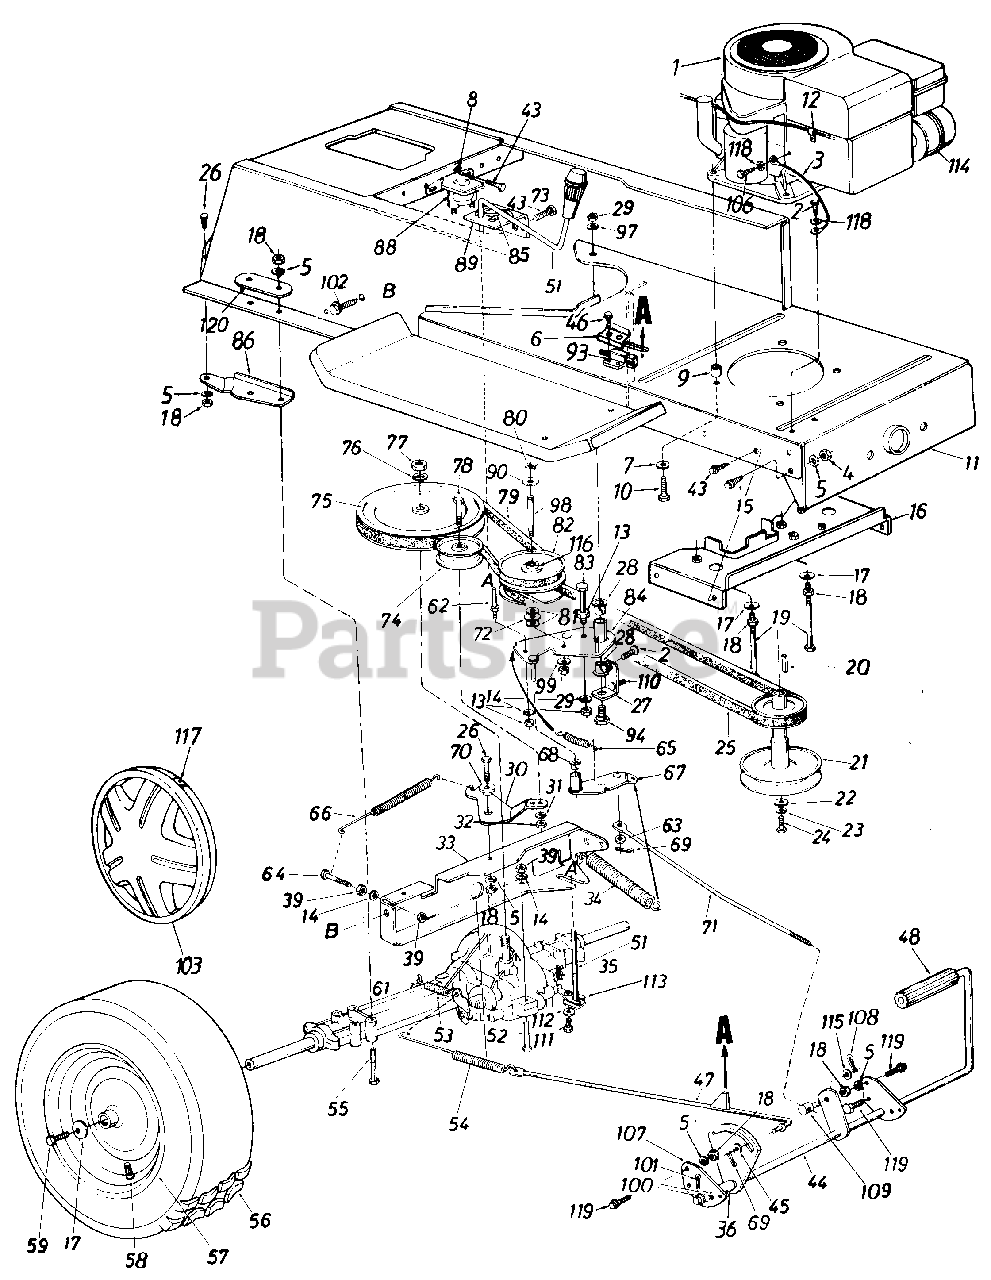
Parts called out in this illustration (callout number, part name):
1	Engine
2	Hex Wash. AB-Tap Scr. 5/16" x .75"
3	Electric Ground Wire
4	Hex Nut 5/16-24 Thd.
5	L-Wash. 5/16" I.D.
6	Switch Plate
7	Fl-Wash. .406" I.D. x 1.25"
8	Ext. L-Wash. 1/4" I.D.
9	Spacer
10	Hex L-Wash. Tap Scr. 3/8-16 x 1.5 Lg.
11	Lower Frame Ass'y.
12	Speed Clip
13	Hex Nut 1/4-20 Thd.
14	L-Wash. 1/4" I.D.
15	Rib Neck Bolt 5/16-24 x .84" Lg.
16	Belt Guard Brkt. Ass'y.
17	Bell-Wash. .345" I.D. x .88"
18	Hex Nut 5/16-18 Thd.
19	Hex Bolt 5/16-18 x 4.0"
20	Sq. Key 1/4" x 1/4" x 2.00"
21	Engine Pulley
22	Fl-Wash. 7/16" I.D. x 1.25"
23	L-Wash. 7/16" I.D.
24	Hex Bolt 7/16-20 x 1.50" Lg.
25	Variable-Speed Belt
26	Hex Bolt 5/16-18 x .75" Lg.
27	Bearing Shaft Bracket Ass'y.
28	Flanged Nyliner Brg. 5/8" I.D. x .88" Lg.
29	Hex Nut 3/8-24 Thd.
31	L-Wash. 3/8" I.D.
32	Hex Nut 3/8-24 Thd.
33	Transaxle Support Brkt.
34	Ext. Spring .94" O.D. x 7.58"
35	Inter. Cott-Pin
36	Spacer.63" I.D.
39	Hex Nut 1/4-28 Thd.
43	Hex Wash. Hd. S-Tap Scr. 1/4-20 x .50" Lg.
44	Clutch/Brake Pedal Ass'y.
45	Fl-Wash.
46	Truss Mach. Scr. B-Tap Scr. #10 x .5" Lg.
47	Brake Rod Ass'y.
48	Foot Pad
51	Shift Lever Ass'y.
52	Hex Bolt 1/4-28 x 1.75" Lg.
53	Ext. Spring .38" O.D. x 2.5"
54	Ext. Spring 7.08"
55	Hex Bolt 5/16-18 x 2.75"
57	Wheel Rim Only
58	Air Valve
59	Hex Bolt 5/16-24 x .75" Lg.
61	Brake Return Spring Anchor
62	Belt Guard Pin 1/4-20 Thd.
63	Fl-Wash. .34" I.D. x .68" O.D.
64	Hex Bolt 1/4-28 x 1.25" Lg.
65	Ext. Spring
66	Ext. Spring .62" O.D. x 6.12"
68	Flanged Bearing
69	Cotter Pin 3/32" Dia.
70	Shoulder Spacer .27" Lg.
71	Speed Control Link
72	Truss Bearing .56 Dia. x 1 .25"
73	Shift Knob
74	Fl-Idler Pulley 3.25" x .75"
75	"V"-Pulley
76	L-Wash. 1/2" I.D.
77	Hex Jam Nut 1/2-20 Thd.
78	Hex Bolt 3/8-24 x 1.75" Lg.
79	Variable Speed Belt
80	Snap Ring .56" Dia.
81	Fl-Wash.
82	Variable Speed Pulley Ass'y. 5" O.D.
83	Hex Bolt 1/4-20 x 3.25" Lg.
90	Teflon Washer .565" I.D.
93	Safety Switch (Clutch)
94	Shld. Bolt 3/8-24 x 3.12" Lg.
97	Bell-Wash. .38" I.D. x .88"
98	Shaft .56" Dia. x 3.875" Lg.
99	Bell-Wash. .39" I.D. x 1.12"
100	Fl-Wash. .64" I.D. x .94"
101	Cotter Pin 1/8" Dia. x 1.25"
102	Hex Wash. Hd. Scr. 5/16-18 x.62" Lg.
103	Hub Cap
106	Truss Mach. Scr. 5/16-18 x .75" Lg.
109	Ferrule
110	Hex Bolt 5/16-18 x 1.0" Lg. (Grade 5)
111	Hex Bolt 1/4-28 x .50" Lg.
112	Bell-Wash. .265" I.D. x .75"
113	Shift Lever Link Ass'y.
114	Muffler
115	Fl-Wash. .385" I.D. x .62"
116	Needle Brgs.
117	Spring Clip
118	External L-Wash. 5/16" I.D.
119	Hex Wash. TT-Tap Scr. 5/16-18 x .75"
